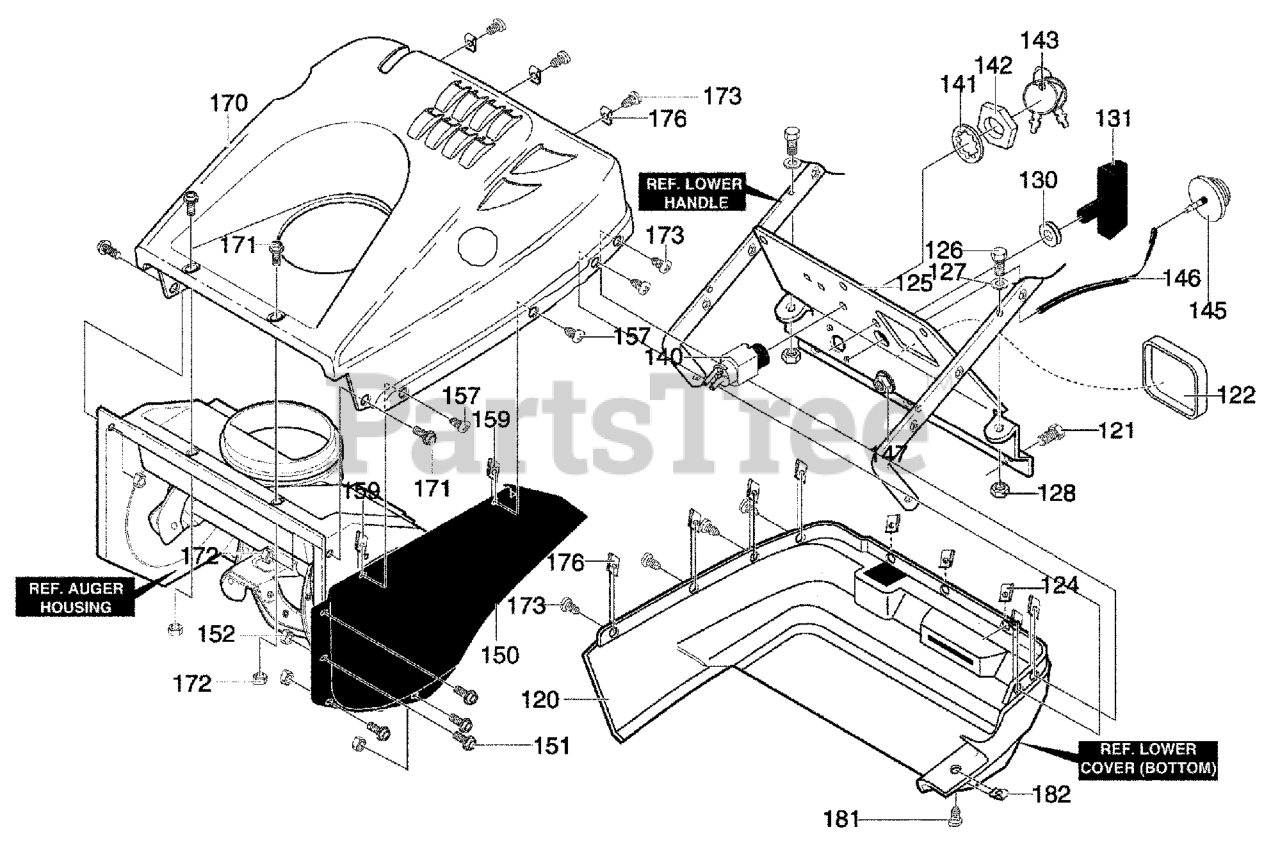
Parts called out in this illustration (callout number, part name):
120	COVER, BOTTOM
121	SCREW, 1/4-14X.75
122	PANEL, SPARK ACCESS
124	NUT, 1/4-10 SPEED J TYPE
125	CONTROL PANEL
126	SCREW, 1/4-20X1.25
127	FLATWASHER
128	NUT, 1/4-20
130	GOMMET & WASHER
131	KNOB T
140	SWITCH, IGNIT.
142	NUT. 5/8-32
143	KEYS & RING
145	PRIMERBULB
146	HOSE PRIM 5.75LG
147	NUT, 1/4-20
150	COVER, BELT
151	SCREW, 10-24X.50
152	NUT, #10-24
157	SCREW, 1/4-14X.75
159	NUT, 1/4-10 SPEED J TYPE
170	COVER, TOP
171	SCREW,#10-24X.50
172	NUT #10-24
173	SCREW, 1/4-14X.75
176	NUT, 1/4-10 SPEED J TYPE
181	SCREW, 1/4-14X.75
182	NUT 1/4-10 SPEED J TYPE
